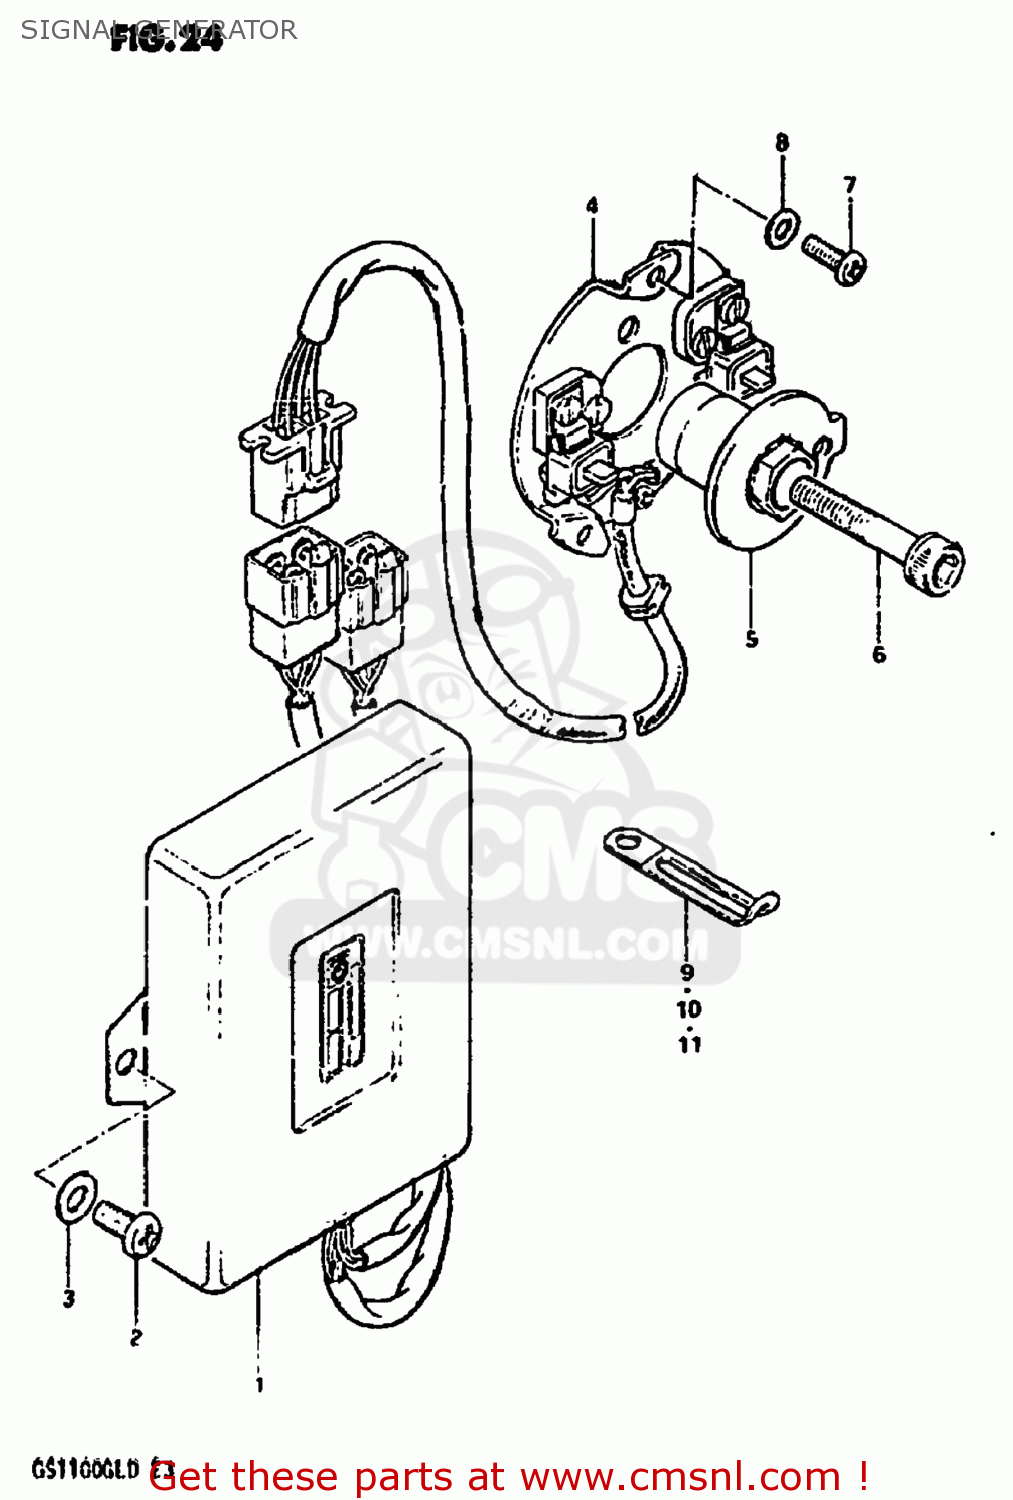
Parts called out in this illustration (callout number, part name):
1	IGNITER UNIT ASSEMBLY
2	SCREW 6X12
3	WASHER
4	STATOR,SIGNAL GENERATOR
5	ROTOR,SIGNAL
6	BOLT
7	SCREW(5X12)
8	WASHER
9	CLAMP L:35
10	CLAMP
11	CLAMP
